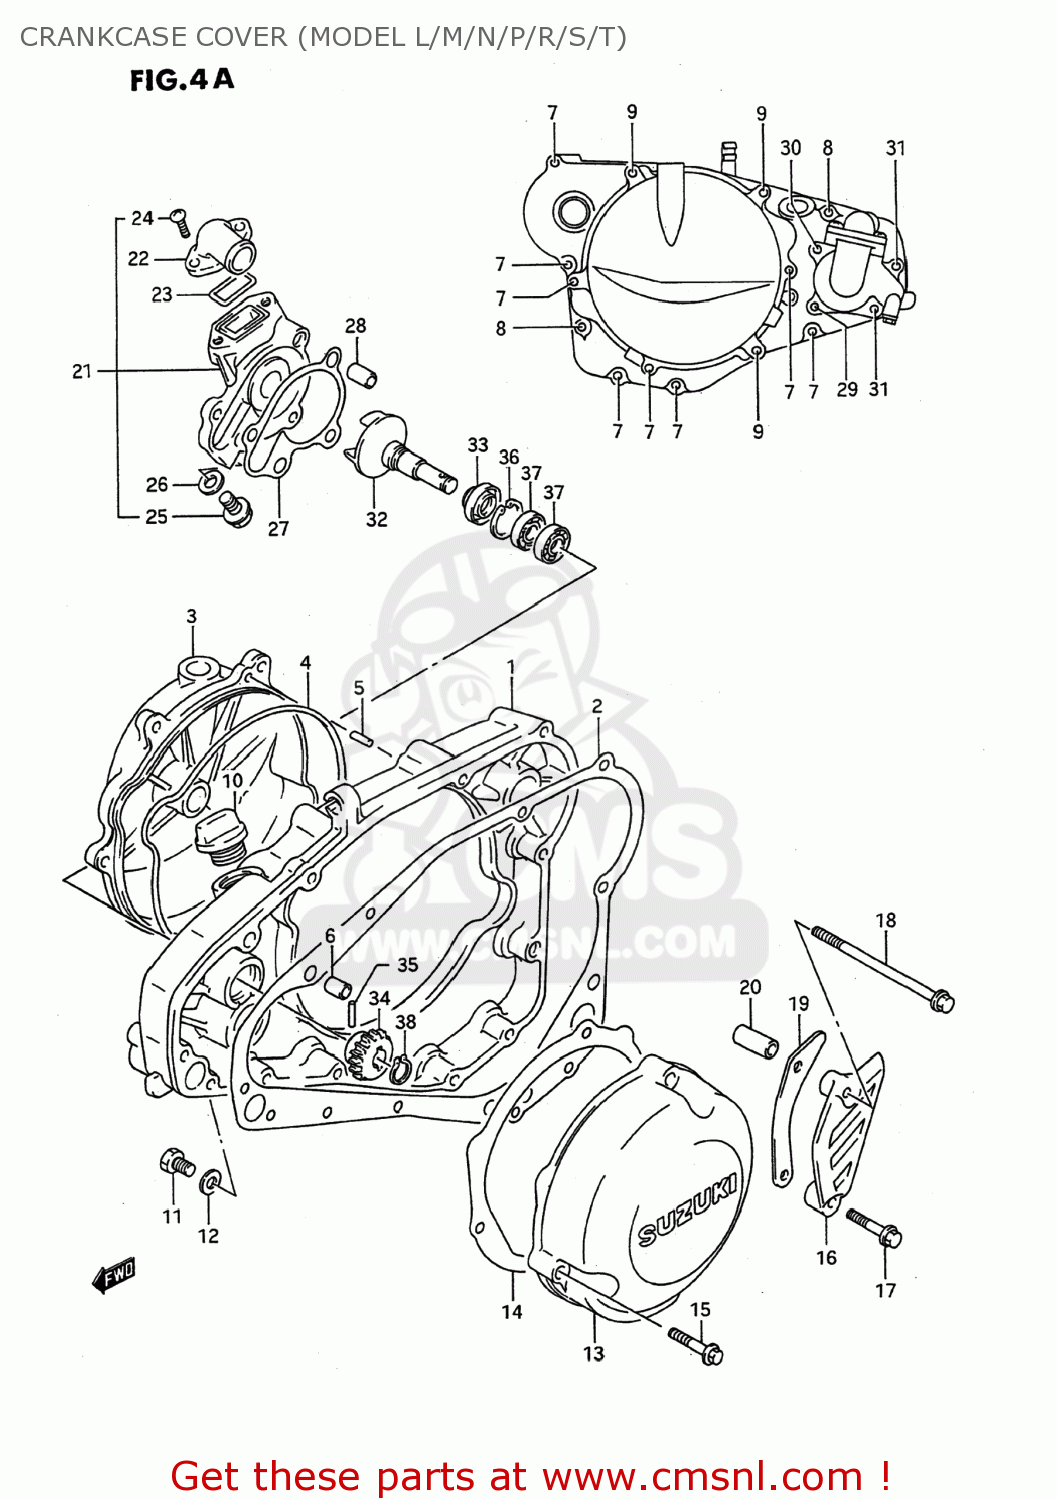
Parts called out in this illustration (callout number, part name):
1	COVER,CLUTCH
2	GASKET,CLUTCH COVER (NAS)
3	COVER,CLUTCH,OUTER
4	O RING,CLUTCH COVER OUTER
5	PIN
6	PIN
7	BOLT
8	BOLT
9	BOLT
10	PLUG SET
11	SCREW(6X10)
12	GASKET(6.2X11X1).2 (NAS)
13	COVER,MAGNETO
14	GASKET,MAGNETO COVER (NAS)
15	BOLT
16	COVER,SPROCKET
17	BOLT
18	BOLT
19	PLATE,FR CHAIN GUIDE(13T)
20	SPACER(6.5X10.5X25)
21	CASE,WATER PUMP
22	CONNECTOR
23	O RING,WATER PUMP CONNECTOR
24	SCREW
25	BOLT
26	WASHER
27	GASKET,WATER PUMP CASE (NAS)
28	PIN
29	BOLT
30	BOLT
31	BOLT
32	IMPELLER,WATER PUMP
33	SEAL,WATER PUMP OIL
34	GEAR,WATER PUMP DRIVEN
35	PIN(3X13.8)
36	CIRCLIP
37	BEARING
38	CIRCLIP,10MM
